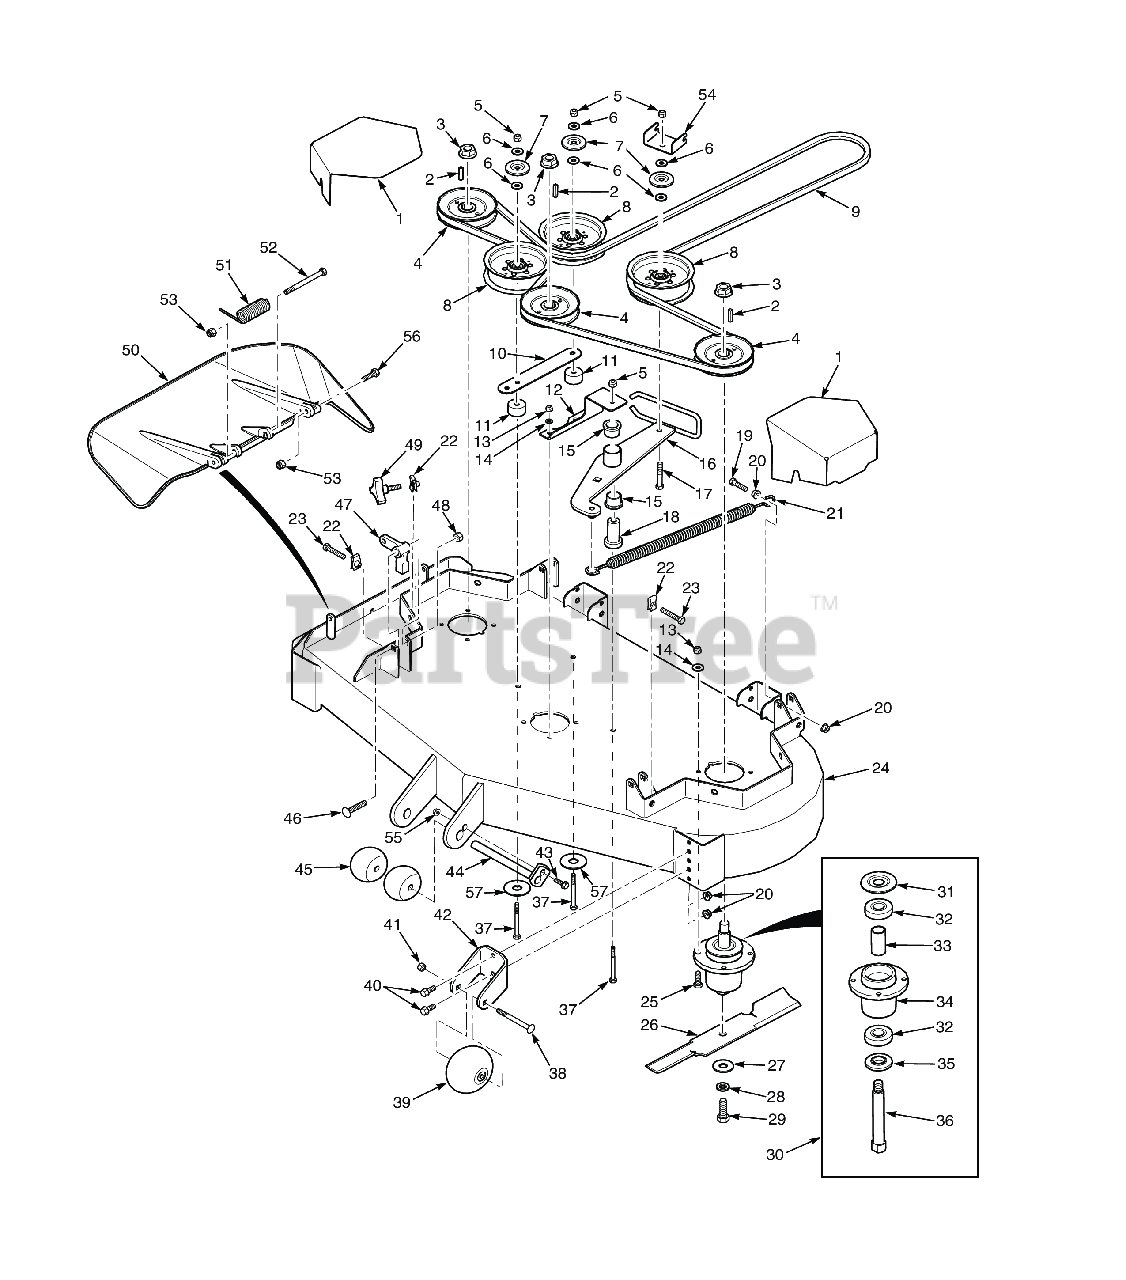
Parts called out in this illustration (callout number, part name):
1	Belt Cover
2	Key, 1/4 x 1/4 x 1.25" Pulley Mtg.
3	Nut, 3/4-16 Spriral Lock
4	Pulley, 5.73" OD - 25mm Bore
5	HEX NUT, ELASTIC STOP LOCK, 3/8-16
6	Flatwasher, 3/8 (.391 x .938 x .105 HD) Grade 8
7	Quick Pin, 5/16" Dia.
8	Pulley, 5" Idler
9	Belt, Cutter Deck
10	Brace, Pulley
11	Spacer, Idler Pulley
12	Support, Idler Pivot - 52
13	Lock Nut, 5/16-18 Elastic Stop Grade 8
14	Lockwasher, 5/16 (.317 x .586 x .078) Helical Spring
15	Bearing, Plastic
16	Idler Arm (incl. item #15)
17	Capscrew, Hex Head 3/8-16 x 2-1/2"
18	Pivot, Idler
19	Bolt, Hex Head 3/8-16 x 1-1/2" Grade 8 Black
20	NUT, 3/8-16 SERRATED FLANGE HEX HEAD
21	Spring, Cutter Deck Idler
22	U-Nut, 3/8-16 (short)
23	Bolt, Hex Head 3/8-16 x 2" Special Lock
24	Cutter Deck w/Decals, SPZ52
25	Bolt, Hex Head 5/16-18 x 1-1/2" (Right Front Engine Mounting, Briggs and Kohler Only)
26	Cutter Blade, 18" (52V)
27	Flatwasher, 5/8-.688 x 1-3/4 x .134 HD
28	Lockwasher, 5/8" Spring
29	Bolt, Hex Head 5/8-11 x 1-1/2"
30	Spindle Assembly
31	Debris Shield
32	Bearing
33	Spacer, Bearing
34	Spindle Housing Assembly
35	Protector, Bearing
36	Shaft, Spindle
37	Bolt, Hex Head, 3/8-16 x 3-1/2"
38	Bolt, Hex Head 3/8-16 x 3-1/2"
39	Bolt, Carriage 3/8-16 x 4"
40	Capscrew, 3/8-16 x 1.0" Serrated Flange Hex Hd
41	Bolt, Hex Head 3/8-16 x 1" Ser. Flg.
42	Bracket, Anti-Scalp Wheel
42	Bracket, Anti-Scalp, (Black)
43	Bolt, Heax Head 5/16-18 x 1" (48V / 52V)
44	Bolt, Hex Head 5/16-18 x 1"
45	Wheel, Anti-Scalp
46	Bolt, Carriage 7/16-14 x 2-1/4"
47	Bolt, Carriage 7/16-14 x 2-1/4"
48	HEX LOCKNUT, ELASTIC STOP, 7/16-14
49	Knob, w/stud 3/8-16 x 1-1/4"
50	Discharge Chute Assy. SFZ52
51	Spring, Discharge Chute
52	Bolt, 5/16-18 x 4-3/4" Hex Head
53	HEX NUT, ELASTIC STOP LOCK, 5/16-18
54	Bracket, Belt Guide
55	Nut, Serrated Flange 5/16-18 (Right Front Engine Mounting, Briggs and Kohler Only)
56	Bolt, Hex Head 5/16-18 x 1-1/2" - Front
57	Flatwasher, 3/8-.406 x 2.25" x .1875
